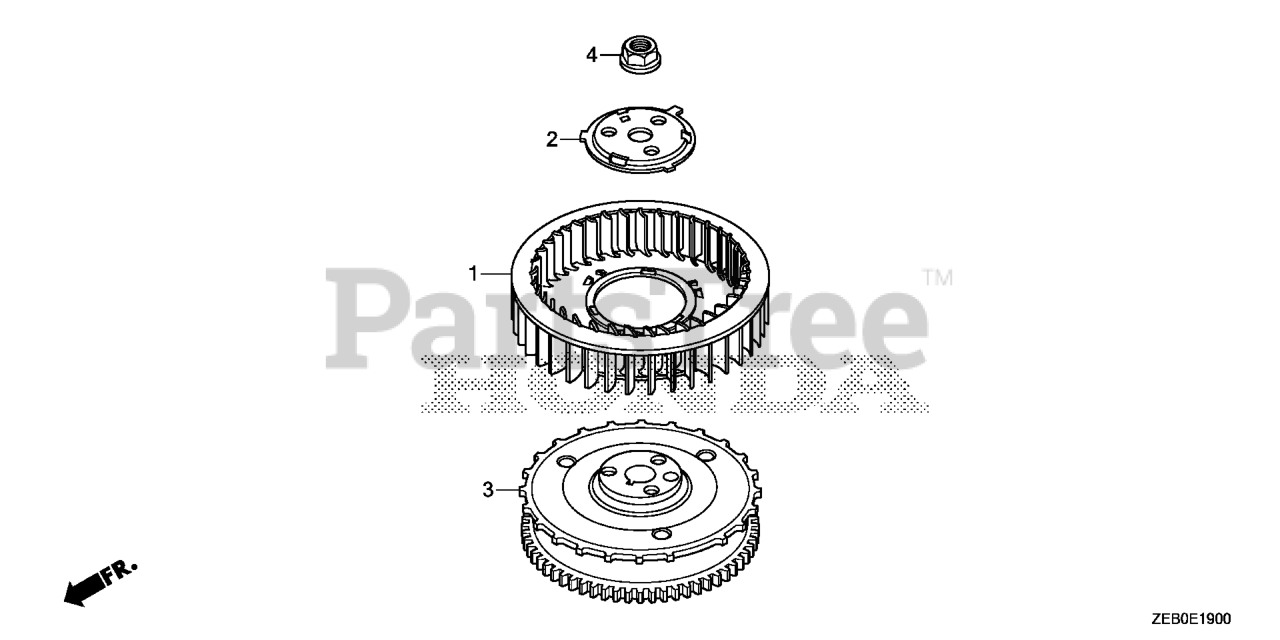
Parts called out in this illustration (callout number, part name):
1	FAN, COOLING
2	PLATE, COOLING FAN SETTING
4	NUT, SPECIAL (20MM)
